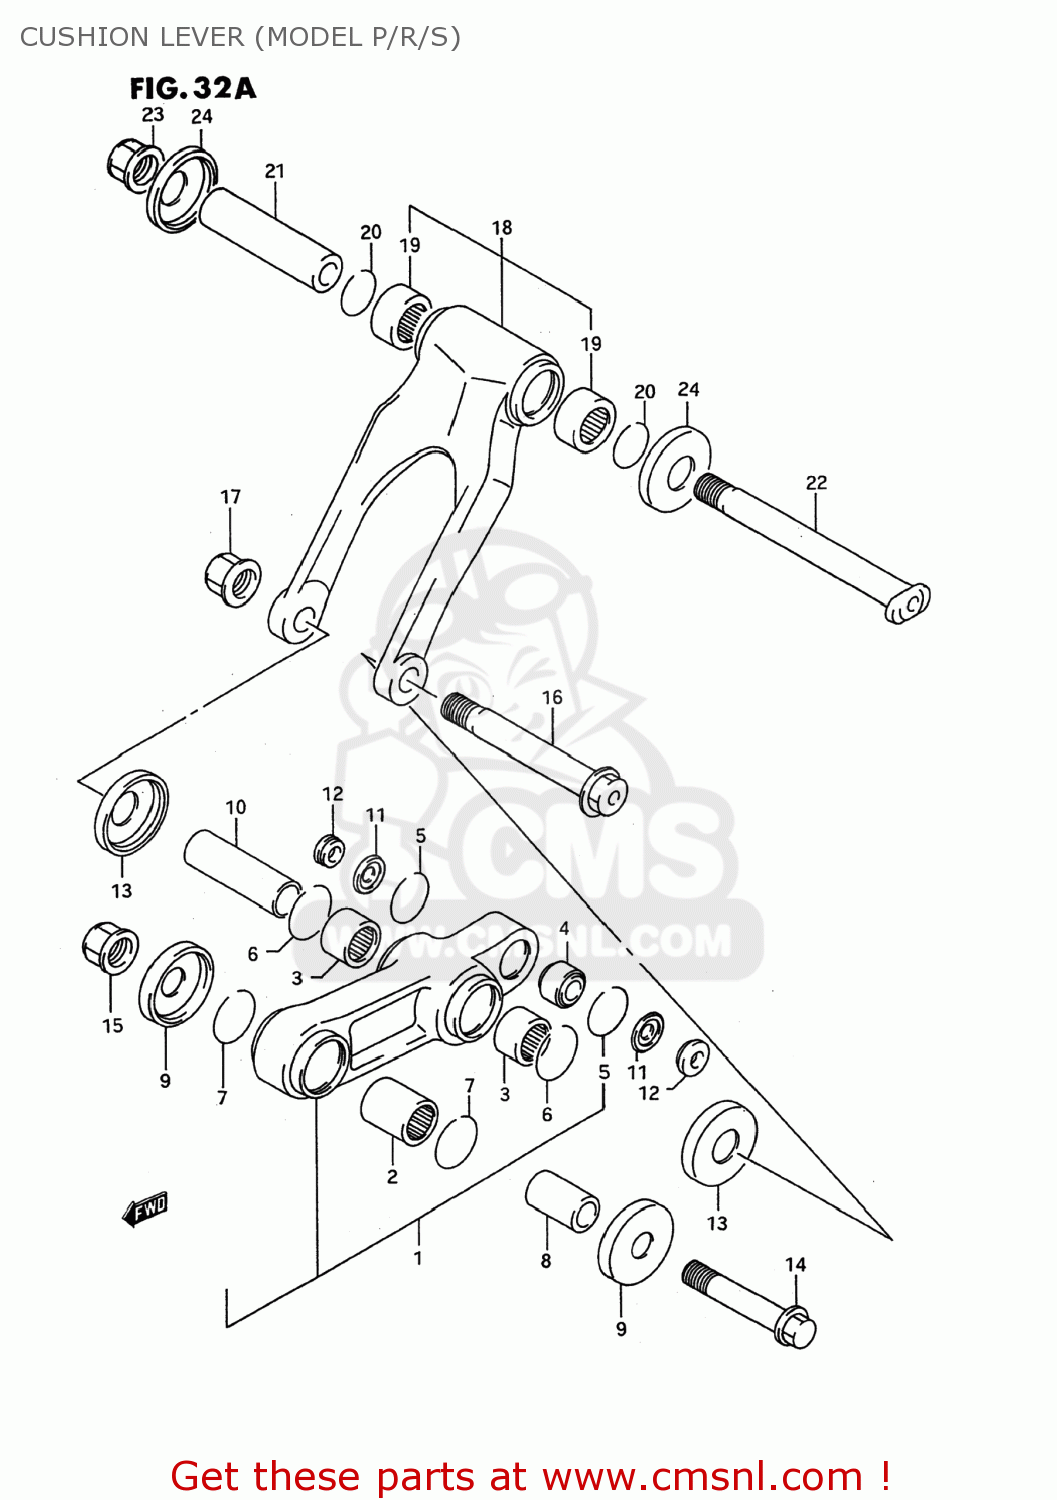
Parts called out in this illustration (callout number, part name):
1	LEVER SET,RR CUSHION
2	BEARING(20X27X25)
3	BEARING(22X28X20)
4	BEARING,RR CUSHION LEVER RR
5	RING,BEARING STOPPER
6	CIRCLIP
7	CIRCLIP
8	SPACER,RR CUSHION LEVER FR
9	SEAL,REAR CUSHION LEVER
10	SPACER,RR CUSHION LEVER CTR
11	SEAL,RR CUSHION LEVER RR DUST
12	SPACER,RR CUSHION LEVER RR
13	SEAL,RR CUSHION LEVER CTR
14	BOLT,RR CUSHION LEVER FR
15	NUT 12MM
16	BOLT,REAR CUSHION LEVER
17	NUT
18	ROD SET,RR CUSHION LEVER
19	BEARING(22X28X20)
20	CIRCLIP
21	SPACER,RR CUSHION ROD
22	BOLT,RR CUSHION ROD
23	NUT
24	SEAL,RR CUSHION LEVER CTR
